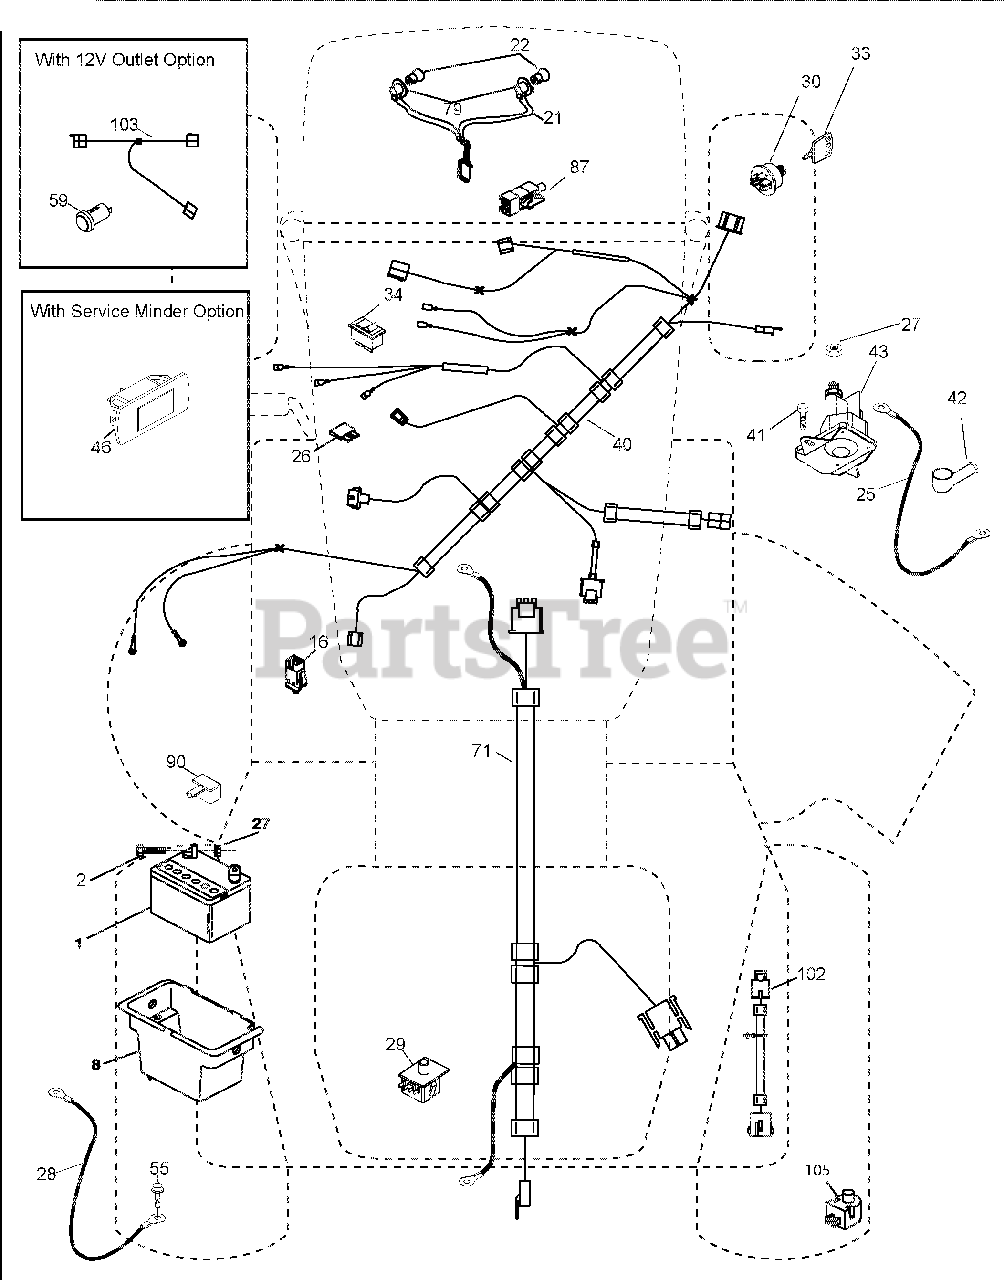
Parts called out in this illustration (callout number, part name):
1	BATTERY.12.VOLT.28.AMP.WET
2	BOLT.HEX.HD.1/4-20UNC X 3/4
8	BOX.BATTERY.MNT.REAR.LT.TEX.BL
16	SWITCH.INTERLOCK.NONO.GRAY
21	HARNESS ASM.LIGHT.22"(4152J)
22	BULB.LIGHT.#1156
25	CABLE.STARTER.6GA.BL/RED.14.5"
26	FUSE.20 AMP.
27	Nut, Keps Hex 1/4-20 unc
28	CABLE.BLACK.22"REAR BATT.TEX
29	SWITCH.SEAT.DP.W/ROS
30	SWITCH.IGN.DLTA.P-IN.ROS
33	KEY/CHAIN.BLISTER PACK.GEN.CE
34	SWITCH.LIGHT/RESET.B/B/RED.
40	HARNESS.IGN.DASH.CBL.YTGT.PRED
41	Screw 1/4-20 x 1/2
42	COVER.TERMINAL.RED
43	SOLENOID.W/BRASS PLUNGER.2005
55	SCREW.5/16-18X3/4.SMGML.TAP/R
71	HARNESS.IGN.CHASS.TEX.REAR.BAT
79	SOCKET ASM.BULB.TWISTLOCK
87	SWITCH.INTRLCK.CLUTCH.CABLE.TX
90	COVER.TERMINAL.BATTERY.RR.TEX
102	PIGTAIL REV. GT VATR
105	SWITCH.REVERSE.TT.PEDAL CONTRO
